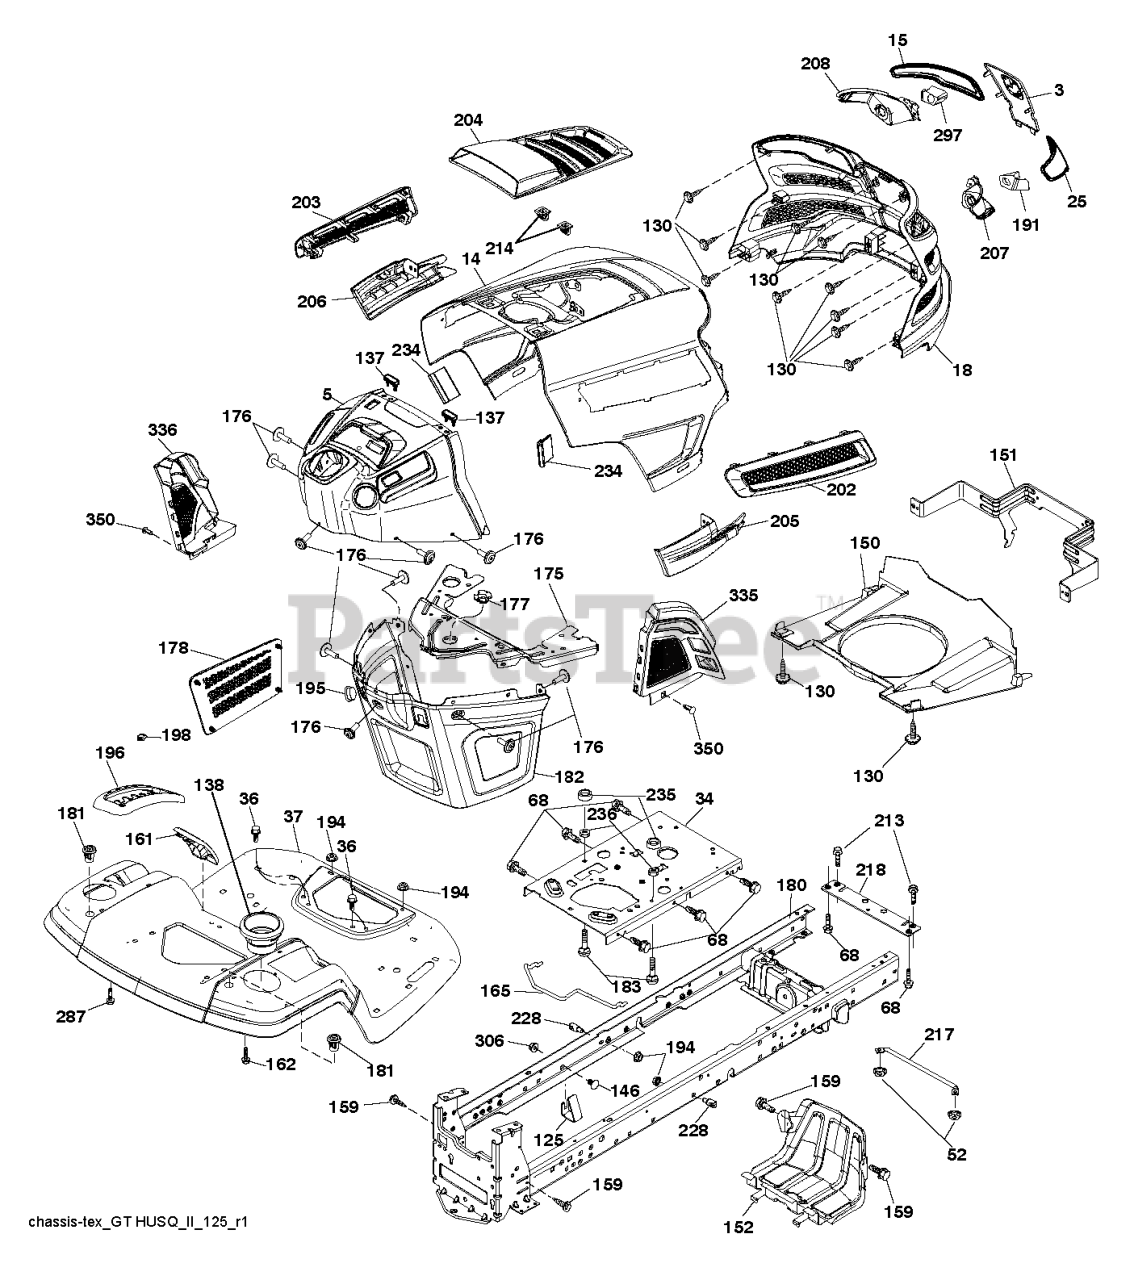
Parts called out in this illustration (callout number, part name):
3	APPLIQUE.SUBASM.GT.HUSQ.II
5	DASH.UPR.GT2.SRV.MIND.MAN.CLUT
14	HOOD.ASM.HUSQVARNA.GT.TEX.ORAN
15	LENS.HEADLIGHT.LH.GTII.2011
18	GRILLE.SUBSTRATE.2011.
25	LENS.HEADLIGHT.RH.GTII.2011
34	PLATE.ENGINE.WELDED.CHASSIS
36	SCREW 5/16"
37	FENDER.ERGO.LT.W/CPH.W/FW.ORNG
52	LOCKNUT
68	Screw 5/16-18 x 1/2 Hex, Self Tapping 5/16-18 x 1/2
125	CLIP.FUEL.LINE
130	SCREW.#10 X 0.750.BOS
137	BUMPER DASH
138	HOLDER.CUP.LT.GREY
146	BOLT.RDHD.SHT.SQNK.3/8-16X5/8
150	AIR.DUCT.GTV.BLACK
151	BRACKET.PIVOT.HOOD.GT.HUSQ.II
152	SHIELD.BROWNING.PNT.GT.V2
159	SCREW, 3/8-16X3/4
161	WINDOW.FUEL.LT.HUSQ.TEX.498
162	SCREW.HI-LO.CONSOLE
165	SUPPORT.TANK.REAR.W/TEX
175	PLATE.CROSSMEMBER.HUSQ
176	SCREW.#10-24X5/8.RN.QU
177	BUSHING, STEERING
178	CARGO.ASM.NET.TXGT.W/C
180	CHASSIS
181	BUSHING.MNT.FEND.CRGO.TEX.49
182	DASH.LOWER.COMMON.12V.ADAPTOR
183	BOLT.5/16-18X1-1/4 FULL THD
191	INSERT.REFLECTIVE.RH.HUSQ.GTII
194	NUT LOCK HEX FLANGE 5/16-18
195	PLUG.HOLE.DASH.LOWER.12V.BLK
196	CONSOLE.DECK.LIFT.GREY
198	INDICATOR.DECK.LIFT.RED
202	VENT.SIDE.RH.GT.HUSQ.II.
203	VENT.SIDE.LH.GT.HUSQ.II.498
204	VENT.TOP.HUSQ.GT2
205	SIDE.TRIM.RH.GT.HUSQ.II
206	SIDE.TRIM.LH.GT.HUSQ.II.GRAY
207	BEZEL LIGHT.RH.GT.II.MYLAR
208	BEZEL LIGHT.LH.GT.II.MYLAR
213	BOLT
214	CLIP.RETAINER.TINNER.
217	ROD.PIVOT.HOOD
218	X-PIECE.HOOD.STOP.NON/
228	STUD.FASTNER.W/ANTI-ROTATE
234	BUMPER.HOOD.TEX.HUSQVARNA
235	SPACER FENDER
236	NUT.CENTERLOCK.5/16-
287	SCREW 1/4X20
297	INSERT.REFLECTIVE.LH.HUSQ.GTII
306	NUT LOCK FLG 3/8-16 UNC
335	COVER.LOWER.DASH.RH.BLACK
336	COVER-LH.LOWER.DASH.GT2.BLACK
350	CLIP.X-MAS.TREE
